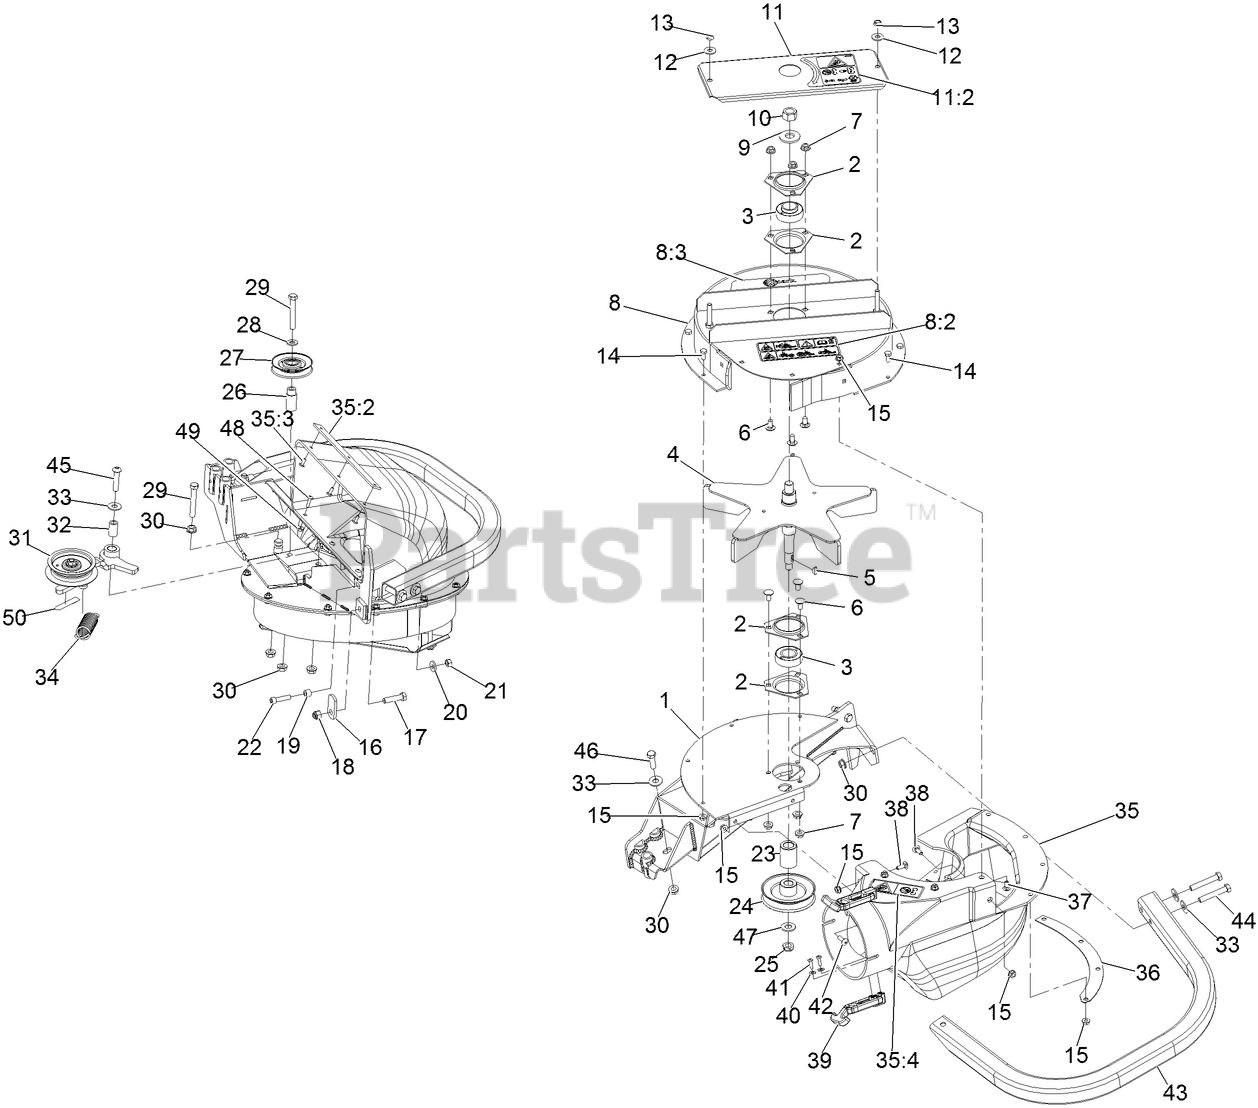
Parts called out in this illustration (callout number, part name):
1	FRAME- BLOWER
2	HOUSING-FLANGE
3	BEARING
4	IMPELLER
5	KEY-WOODRUFF
6	SCREW-CARR
8	UPPER-HOUSING W/DECAL
8:2	DECAL-ULTRAVAC S-SERIES
8:3	DECAL-WARNING
9	WASHER-SPRING
10	NUT-HEX
11	COVER-BEARING W/DECAL
11:2	DECAL-WARNING
12	WASHER-FLAT
13	NUT-LOCK, NI
14	SCREW-HH
16	LATCH-CATCHER, GRASS
17	SCREW-HH
18	NUT-LOCK, NI
19	BUSHING, LOCATOR
20	WASHER-SPRING
21	NUT-HEX
22	SCREW-HSH
24	SHEAVE-BLOWER
25	NUT-LOCK, NI
27	IDLER-INSIDE
28	WASHER-FLAT
29	SCREW-HH
30	NUT-HHF, WHIZ
31	ASM, IDLER
32	BUSHING-PIVOT, IDLER
33	WASHER-FLAT
34	SPRING-IDLER
35	ASM,BLOWER CHUTE LHP
35:2	PLATE-REINFORCEMENT
35:3	RIVET-BLIND
35:4	Decal-Blower-Impeller Hazard
36	PLATE-BACKING, BLOWER
37	SCREW-CARR
38	BOLT-CARR
39	LATCH-RUBBER
40	WASHER-FLAT
41	SCREW-PPH
44	SCREW-HH
45	SCREW-HSBH
46	SCREW-HH
47	WASHER-FLAT
48	SCREW-HEAD, TRUSS
50	DECAL-WARNING
